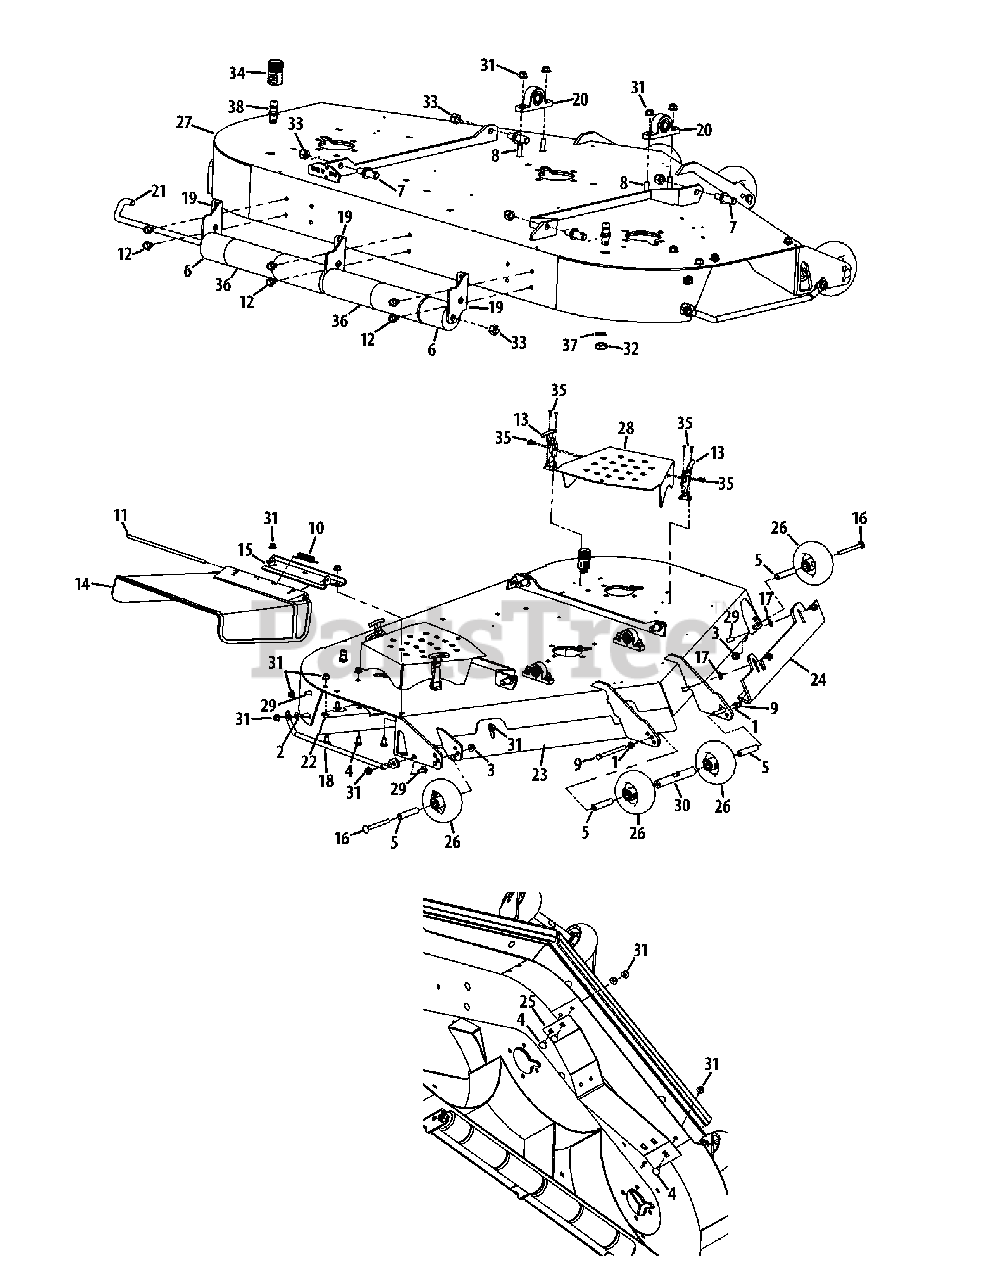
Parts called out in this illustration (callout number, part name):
1	Lock Washer, 3/8
2	Washer, 3/8
3	Flange Lock Hex Nut, 3/8-16
4	Carriage Bolt, 3/8-16 x .75
5	Wheel Spacer
6	Grass Catcher Roller
7	Pin, 5/8 Dia. x 1.2
8	Carriage Bolt, 3/8-16 x 1
9	Hex Cap Screw, 3/8-16 x 4.50
10	Torsion Spring, 0.639 x 2.16
11	Chute Deflector Rod
12	Hex Washer Screw, 3/8-16, .5
13	T-Handle Latch Draw
14	Chute Deflector
15	Chute Deflector Bracket
16	Carriage Bolt, 3/8-16 x 4.00
17	Push Retainer
18	Finger Guard
19	Grass Catcher Roller Bracket
20	Pillow Block
21	J-Hook w/ Threaded Roller
23	Right Hand Front Adjustment Skirt
24	Left Hand Front Adjustment Skirt
25	Baffle, 60" Adjustment
26	Complete Wheel, 5.00 Dia.
27	60" Deck Assembly
28	Deck Belt Cover
29	Carriage Bolt, 3/8-16 x 1.00
30	Ball Wheel Mounting Shaft
31	Lock Nut, Nylon Insert, 3/8-16
32	Hex Nut, M16-1.5
33	Lock Nut, Nylon Insert, 1/2-13
34	Water Nozzle Adaptor
35	Pop Rivet, 3/16
36	Front Roller
37	Lock Washer, 17 x 23.8 x 1.95
38	Deck Water Nozzle
